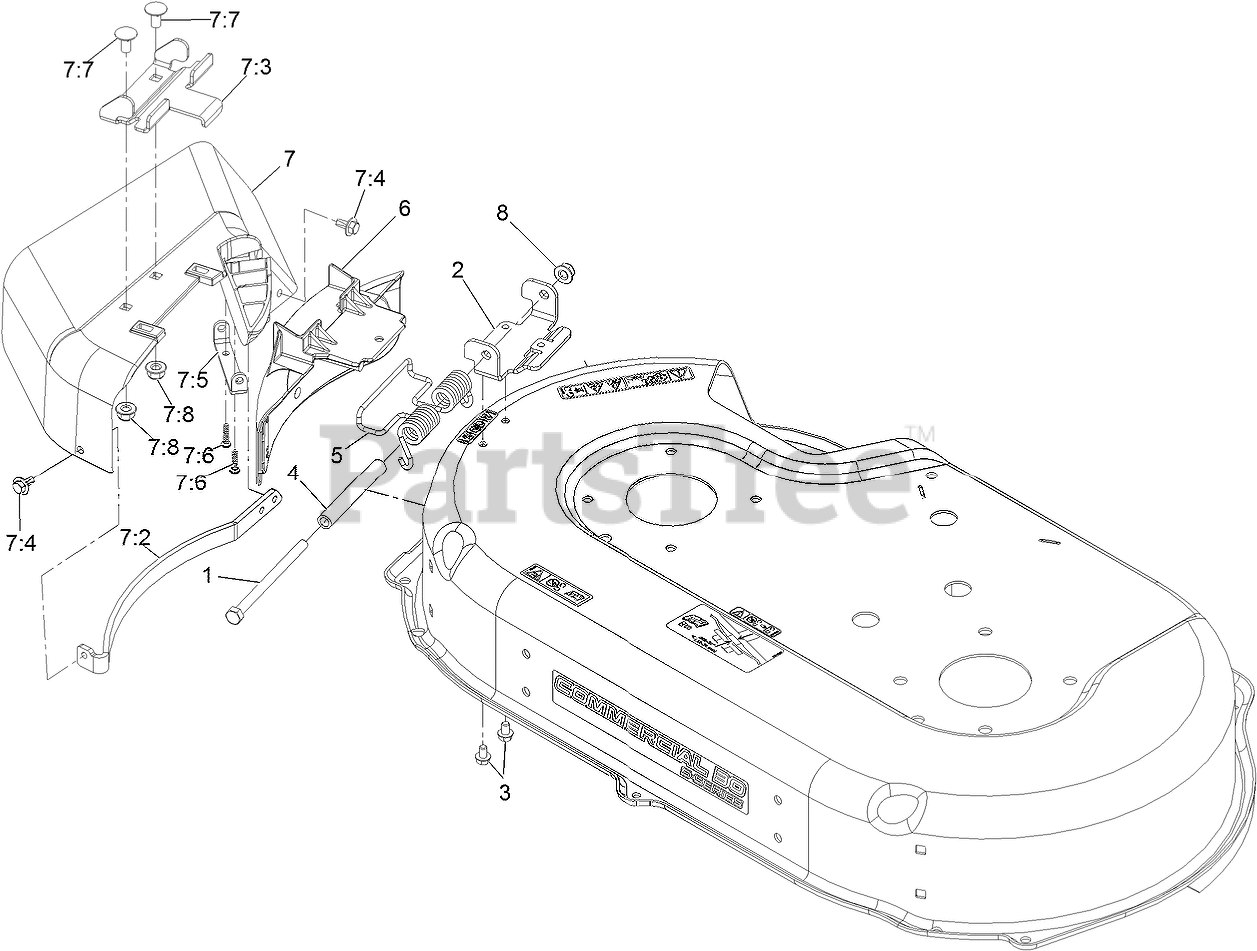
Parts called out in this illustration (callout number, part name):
1	SCREW-HH
5	SPRING-TORSION
6	COVER-DISCHARGE
7	SIDE DISCHARGE CHUTE ASM
7:2	GUARD-CHUTE
7:3	BRACKET-CHUTE
7:4	SCREW-HHFTF
7:5	BRACKET-COVER
7:6	SCREW-PPH
7:7	SCREW-CARR
7:8	NUT-HF, NI
8	NUT-HF, NI
